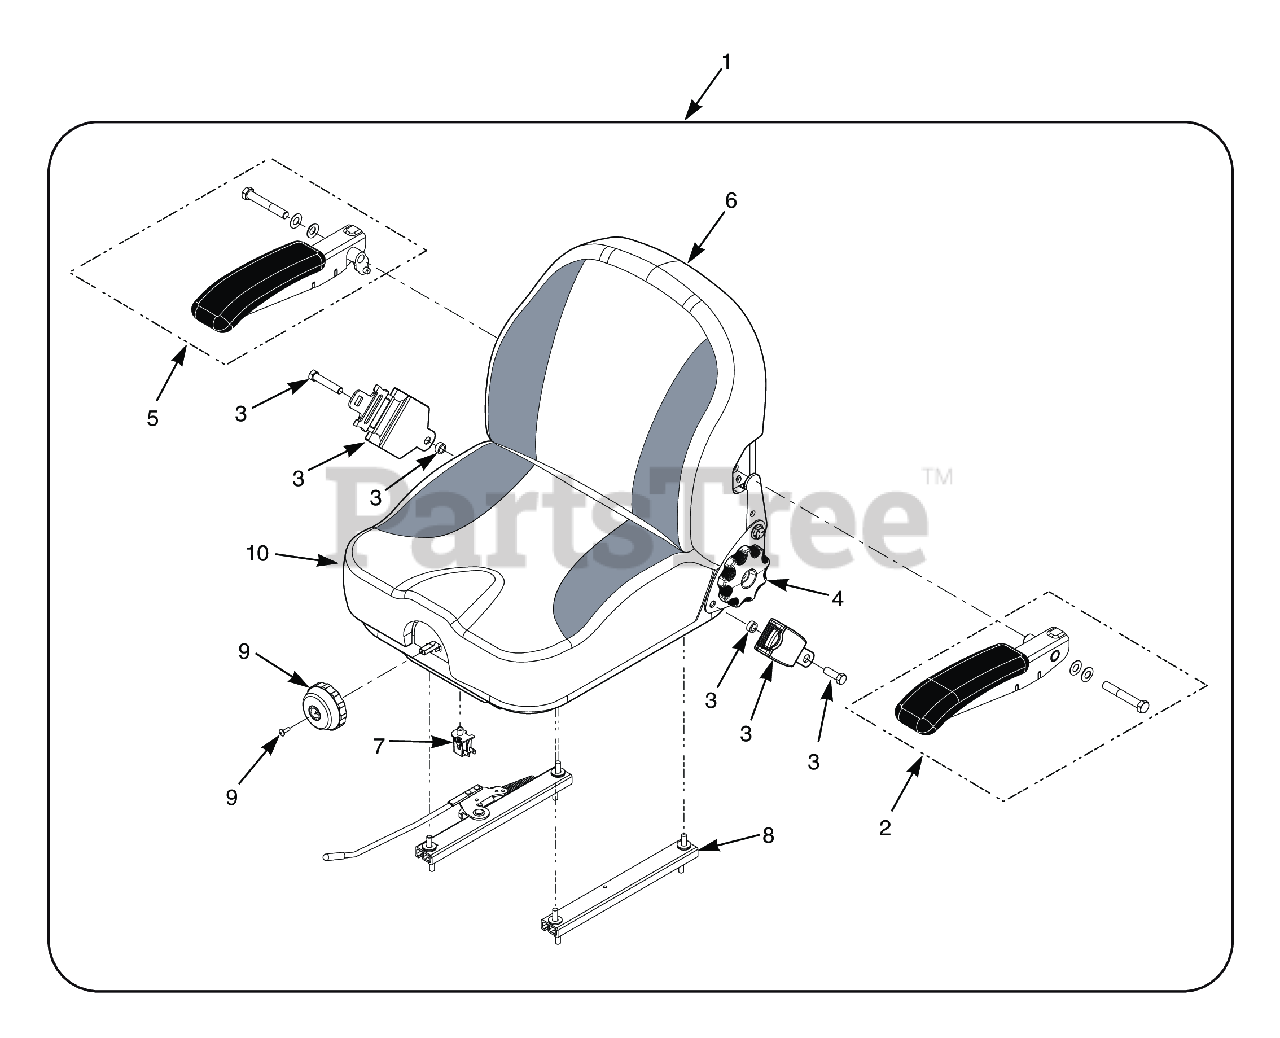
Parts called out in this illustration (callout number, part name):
1	Suspension Seat Assembly w/seat belt
2	Armrest Kit, LH
3	Seat Belt Kit (Suspension Seat)
4	Knob Kit, Recliner
5	Armrest Kit, RH
6	Cover, Back Cushion
7	Switch, Interlock, Normally Open
8	Track Kit
9	Knob Kit, Weight Adjust
10	Cover, Seat Cushion
